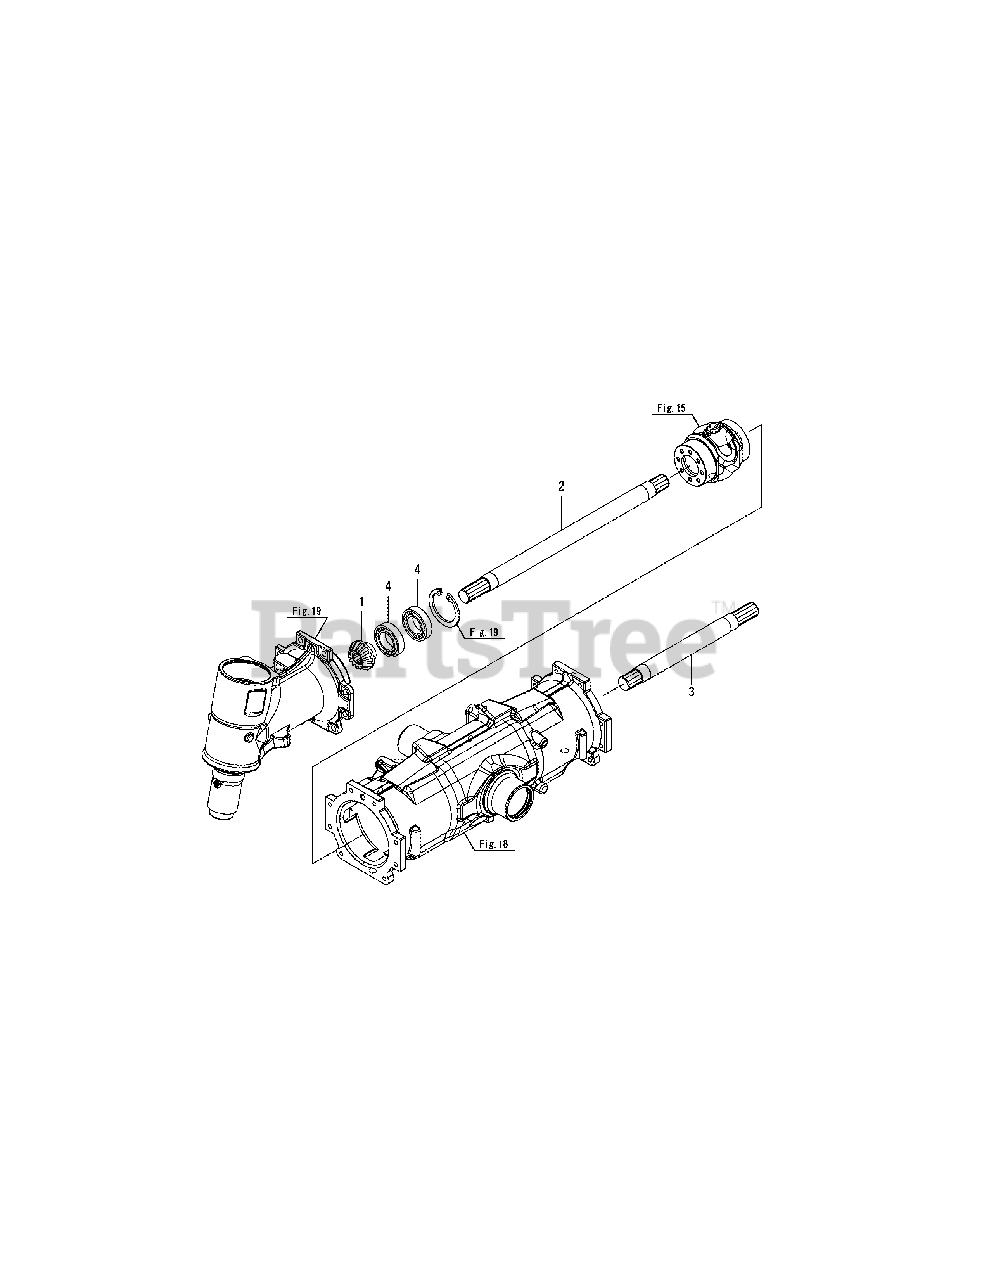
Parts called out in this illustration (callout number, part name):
1	PINION, 1ST SHAFT 12
2	SHAFT L,FRONT 1ST
3	SHAFT R,FRONT 1ST
4	BEARING, HR6209UR
